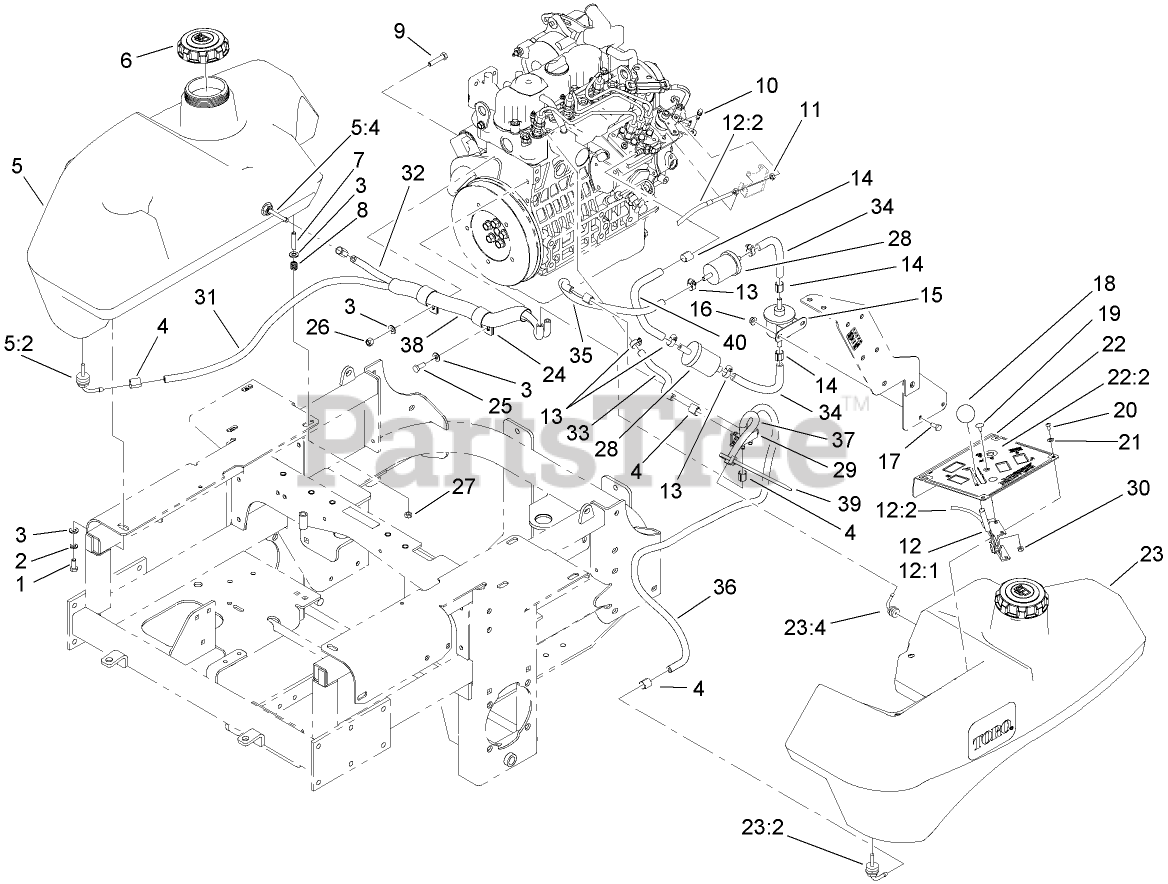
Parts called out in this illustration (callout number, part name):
1	SCREW-HH
2	WASHER-LOCK
3	WASHER-PLAIN
4	CLAMP-HOSE, FUEL
5	RH FUEL TANK ASM
5:2	FITTING-FUEL, BULKHEAD
5:4	Fitting-Fuel, Bulkhead
6	CAP-FUEL, DIESEL
8	SPRING-TANK, FUEL
9	SCREW-HH
10	SWIVEL-STOP, CABLE
11	NUT-JAM
12	THROTTLE CONTROL ASM
12:1	LEVER-THROTTLE
12:2	CABLE-THROTTLE
13	CLAMP-WORM
14	CLAMP-HOSE, FUEL
15	PUMP-FUEL, ELECTRIC
16	NUT-HF
17	SCREW-HH
18	KNOB-BALL
19	BOLT-CARR
20	SCREW-PPH
21	WASHER-SPRING
22	CONTROL PANEL ASM
22:2	DECAL-PANEL, CONTROL
23	LH FUEL TANK ASM
23:2	FITTING-FUEL, BULKHEAD
23:4	Fitting-Fuel, Bulkhead
24	CLIP-LOOM
25	SCREW-HH
26	NUT-LOCK, NI
27	NUT-LOCK, NI
28	FILTER-FUEL
29	VALVE-FUEL, DUAL FLOW
30	NUT-LOCK, NI
31	HOSE-FUEL
32	HOSE-FUEL
33	HOSE-FUEL
34	HOSE-FUEL
35	HOSE-FUEL
36	HOSE-FUEL
37	HOSE-FUEL
38	SLEEVE-FABRIC
39	TIE-PLASTIC
40	HOSE-FUEL
